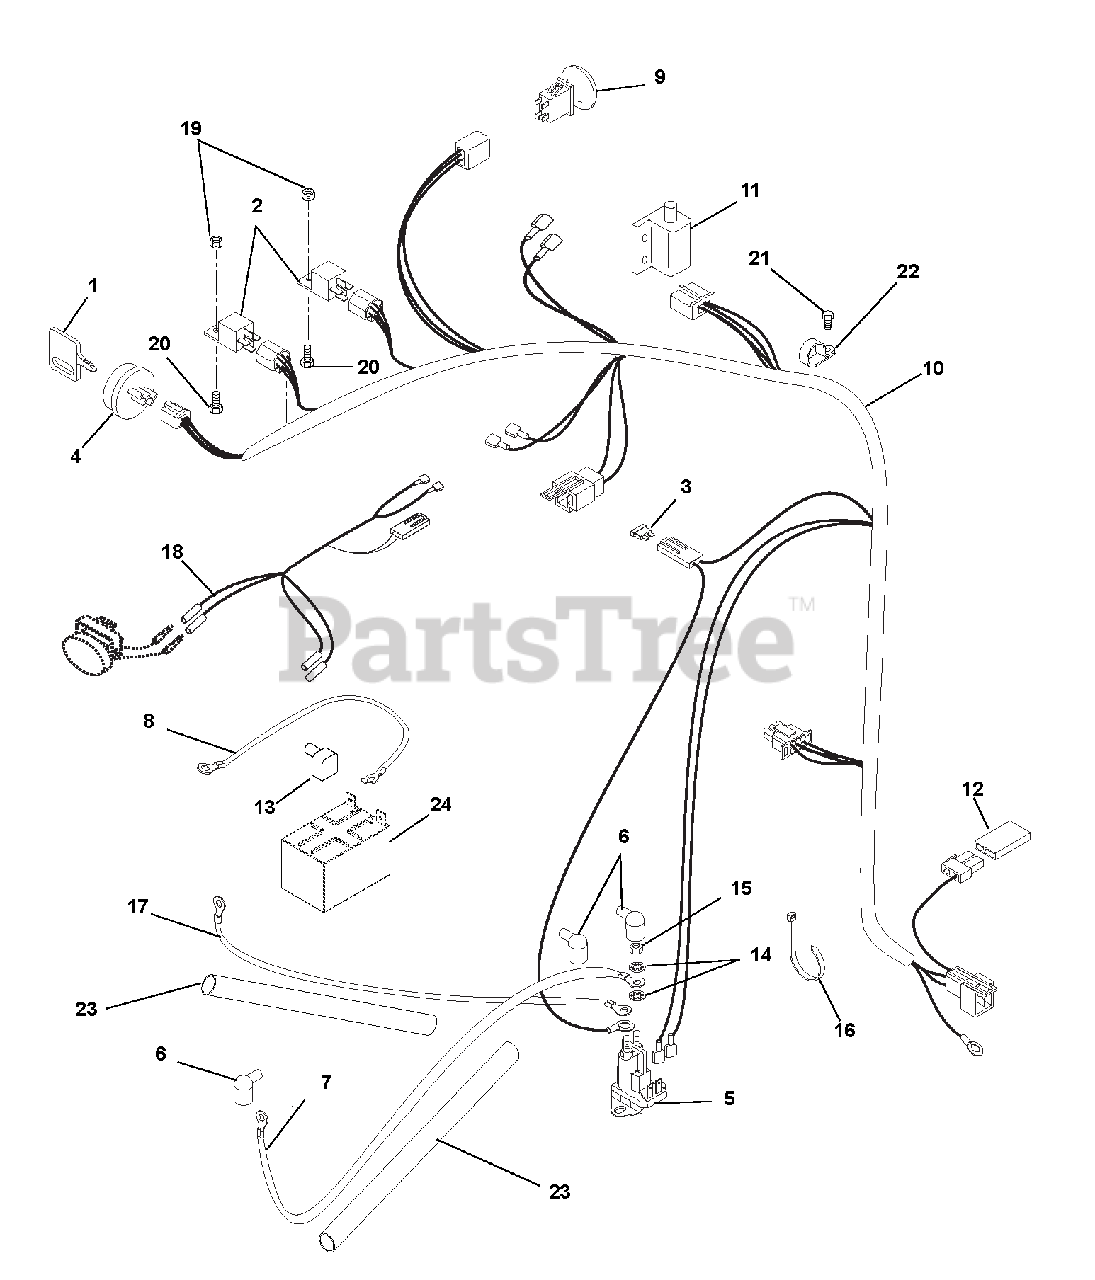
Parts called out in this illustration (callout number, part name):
1	KEY -W/CAP
2	RELAY
3	FUSE-25 AMP ATC TYPE
4	KEY SWITCH
5	SOLENOID, HP RTV
6	BOOT, EYELET TERMINAL
7	STARTER CABLE
8	CABLE-GROUND .25 X 13.00 X .31
9	SWITCH, CLUTCH
10	HARNESS, ZTXL/ZOOMXL
11	SWITCH- DOUBLE POLE N.O./N.O.
12	DIODE, CONNECTOR SHELL
13	INSULATOR
14	WSHR-LOCK INT .31 YWZC
15	NUT-JAM .31-24 YWZC
16	CABLE TIE LG 5-1/2
17	POSITIVE CABLE
18	HARNESS,MINI-Z HEADLIGHT
19	@NUT-LK-NYL 10-24 W/INSRT YWZC
20	@SCR-MCH 10-24X.75 HWH YWZC
21	@SCR-TAP .38-16X.50 HWH TR YWZ
22	CLAMP, CUSHIONED STEEL .75
23	SLEEVE, ANTI-ABRASION
24	BATTERY, 12V; 215 CCA GEP
